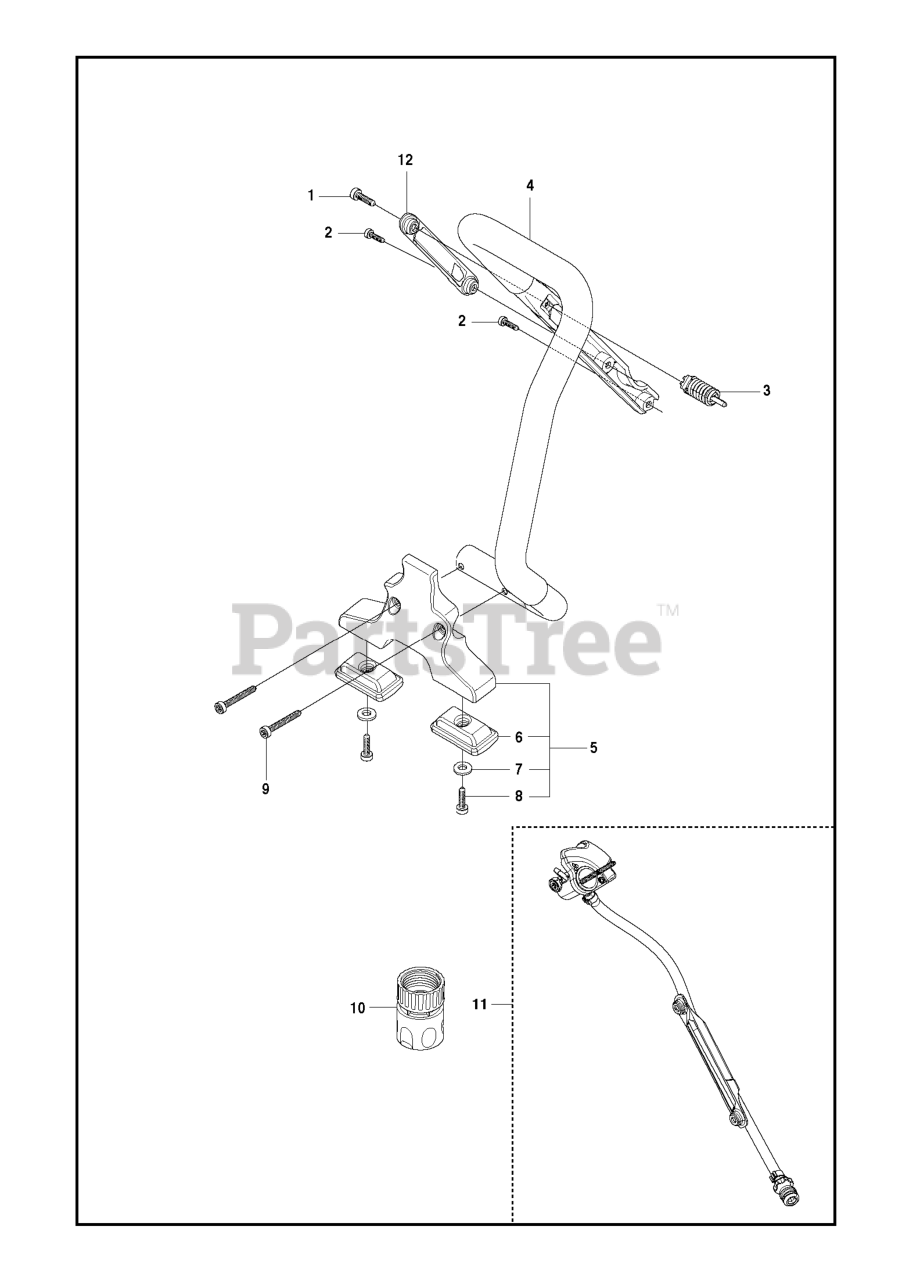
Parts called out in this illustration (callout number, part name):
3	ANTIVIBRATION ELEMENT ASSY
4	HANDLE FRONT
5	GROUND SUPPORT ASSY
6	BASE GROUND SUPPORT
10	FEMALE QUICK COUPLER
10	COUPLER, 1/2" HOSE W/STOP ORIG
11	HOSE KIT VALVE ASSY 25 MM HAND
12	HOSE GUARD
